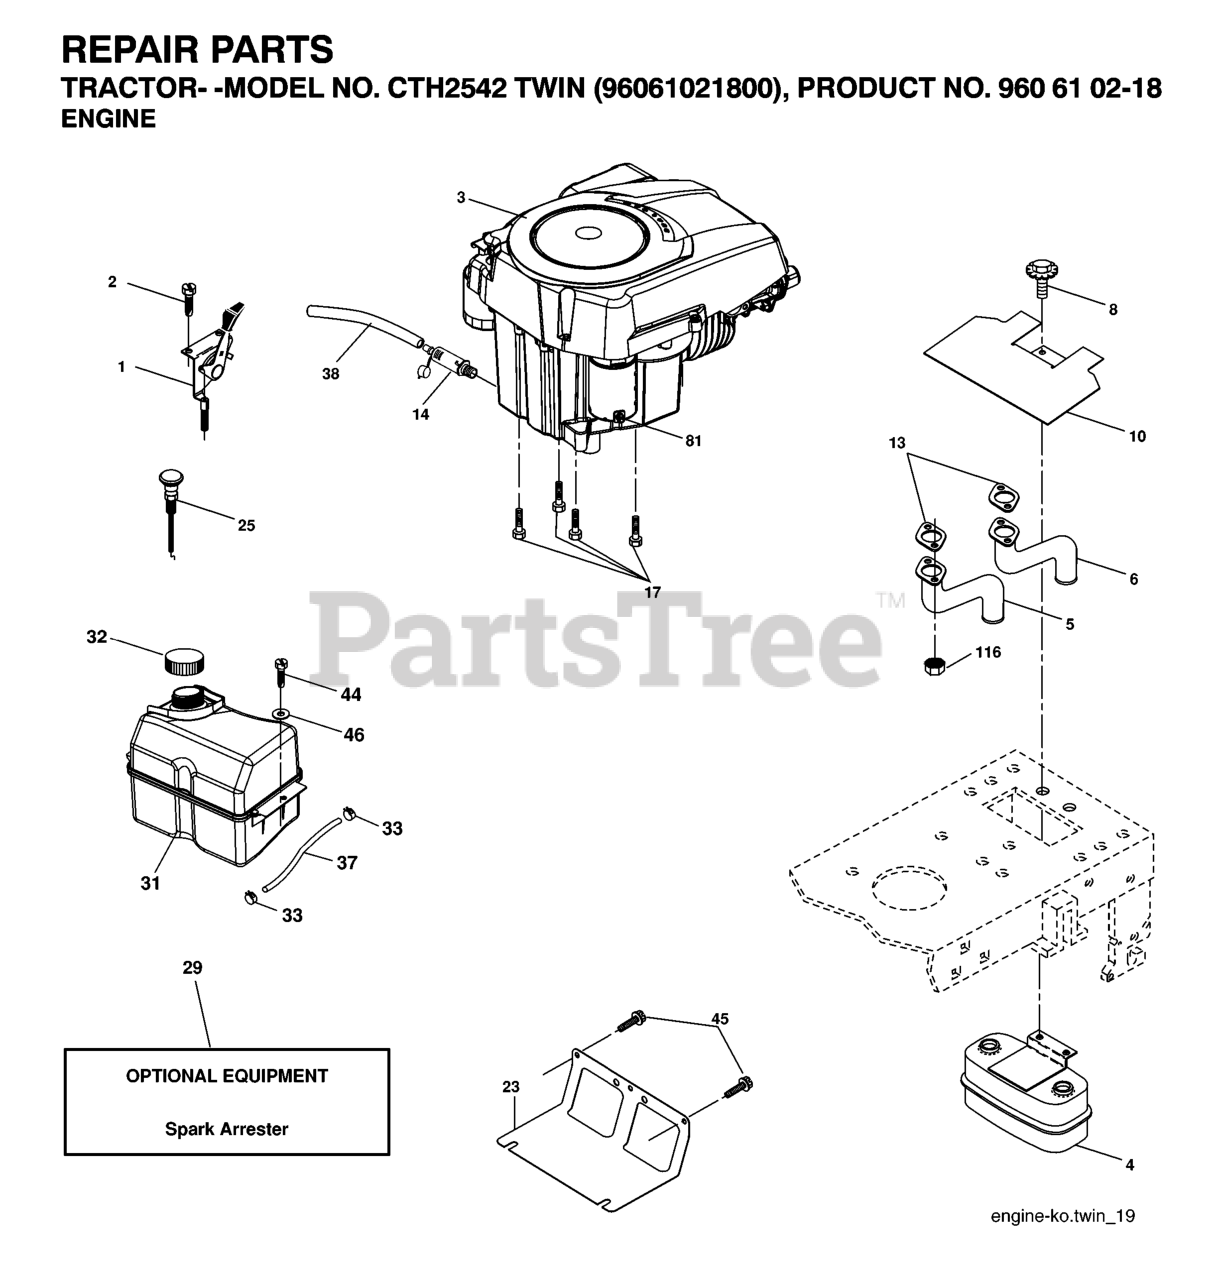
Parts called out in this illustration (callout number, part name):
1	THROTTLE CONTROL
2	SCREW
4	MUFFLER.TWIN.CYL.LOW.TONE
5	RP.PIPE-EXHAUST LH
6	RP.PIPE-EXHAUST RH
8	BOLT.5/16-18UNCX3/4 W/SEMS.BLK
10	RP SHIELD HEAT MUFFLER
14	TUBE, DRAIN OIL ASM.
23	SHIELD.BROWNING.DBR.GUARD
25	CONTROL, CHOKE
29	KIT.SPARK ARRESTOR 794945 B&S
31	TANK.ASM.FUEL.FR.2.5GA.
32	FUEL CAP
33	HOSE CLAMP
37	LINE.FUEL.20
38	PLUG DRAIN OIL EASY
44	SCREW HEXWSHR 1/4-20X3/4
45	SCREW, 3/8-16X3/4
81	NUT
116	NUT.HEX.FLANGE.TOPLOCK
